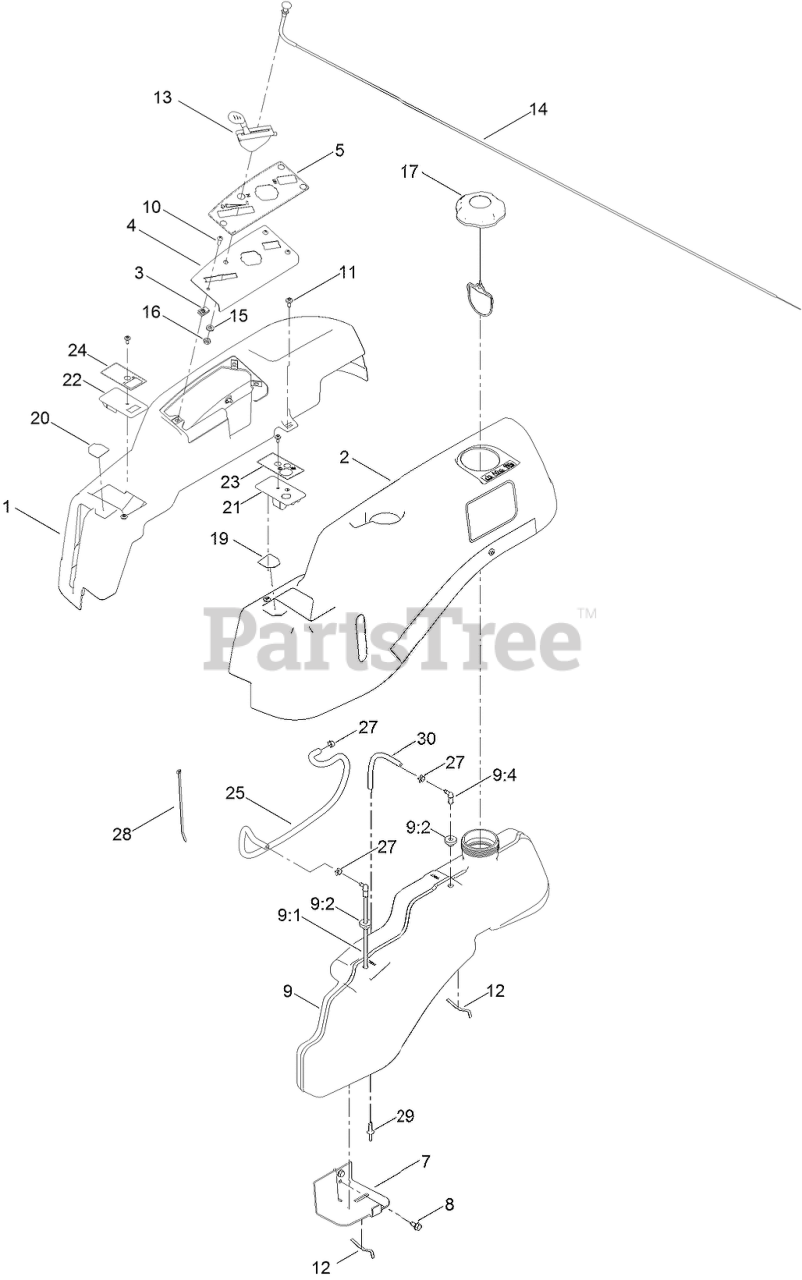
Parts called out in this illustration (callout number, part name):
1	POD-RH
4	PLATE-CONTROL
5	DECAL-PANEL, CONTROL
7	SUPPORT-TANK, FRONT
8	SCREW-HWHTF
9	FUEL TANK ASM
9:1	CONNECTOR-ELBOW, 90 DEG
9:2	BUSHING
9:4	FITTING-PLASTIC
10	SCREW-PRH
11	SCREW-SHOULDER
12	SPRING
13	CABLE-THROTTLE
14	CABLE-CHOKE
15	WASHER-LOCK
16	NUT-HJ
17	CAP-FUEL, RATCHETING
19	DECAL-NMIR
20	DECAL-CONTROL, PEDAL
21	COVER-LH
22	COVER-RH
23	DECAL-KEYCHOICE
24	DECAL-BRAKE, PARKING
25	HOSE-FUEL
27	CLAMP-HOSE
28	TIE-CABLE
29	ADAPTOR-ORIFICE
30	HOSE-FUEL
